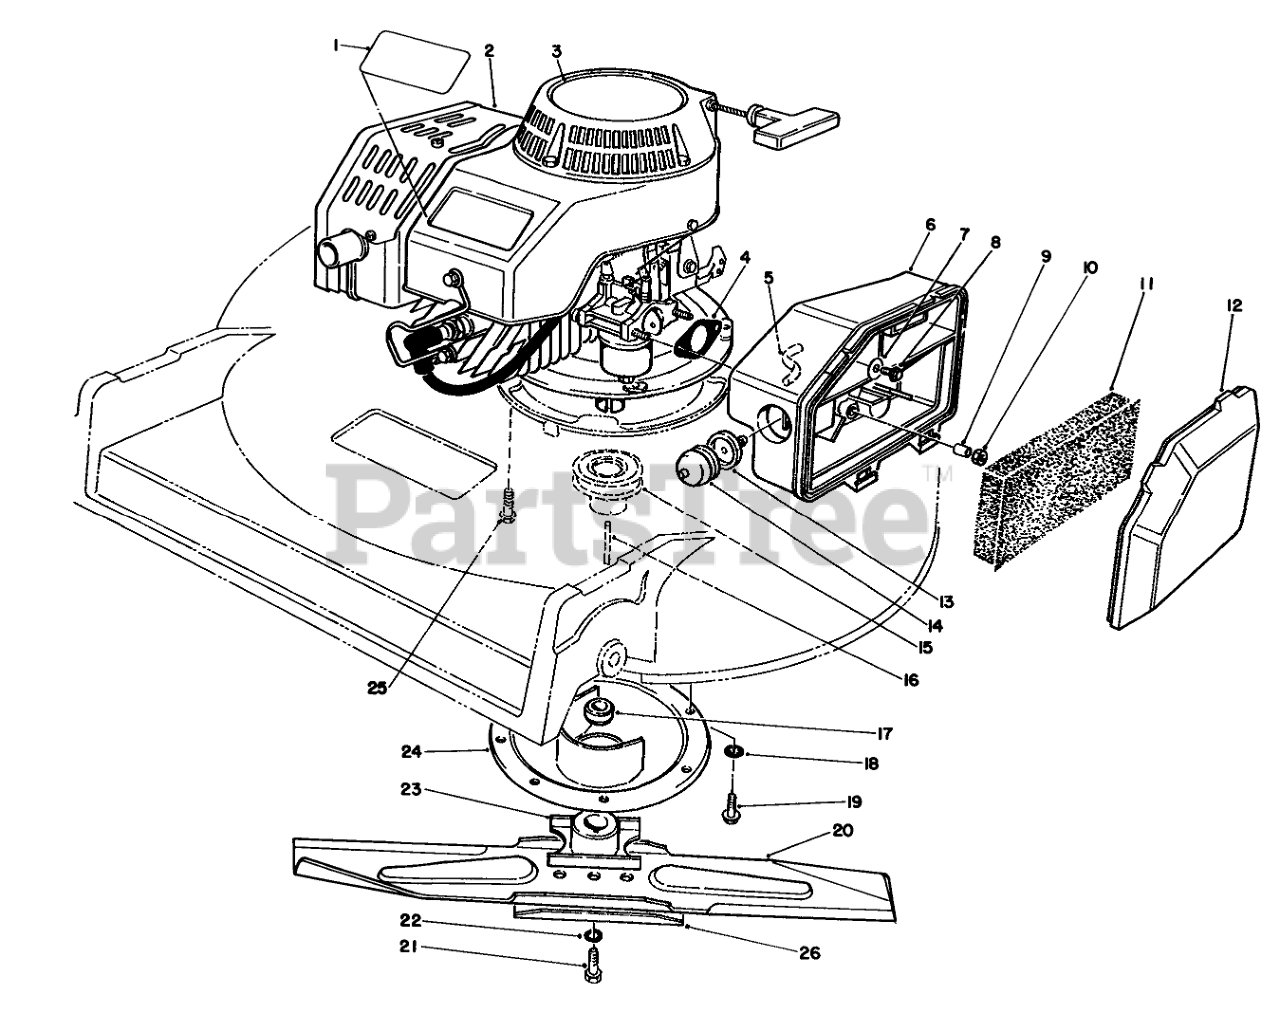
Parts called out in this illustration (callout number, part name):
1	DECAL - PROLINE
2	ENGINE ASM
3	DECAL-2 CYC RECOIL COMM
4	GASKET-AIR CLEANER
5	HOSE-PRIMER
6	BODY-AIR CLEANER
7	WASHER-FLAT
8	SCREW-HH
9	SPACER
11	ELEMENT-AIR CLEANER
12	COVER-AIR CLEANER
13	BODY-PRIMER
14	BULB-PRIMER
15	PULLEY-DRIVER
16	KEY-SQUARE
17	SPACER-BLADE RETAINER
18	WASHER-LOCK, INTERNAL
19	SCREW-HWHTF
20	Blade
21	SCREW-BLADE
22	WASHER-LOCK
23	RETAINER-BLADE
24	PROTECTOR-CRANKSHAFT
25	SCREW-HHF
26	Stiffener
